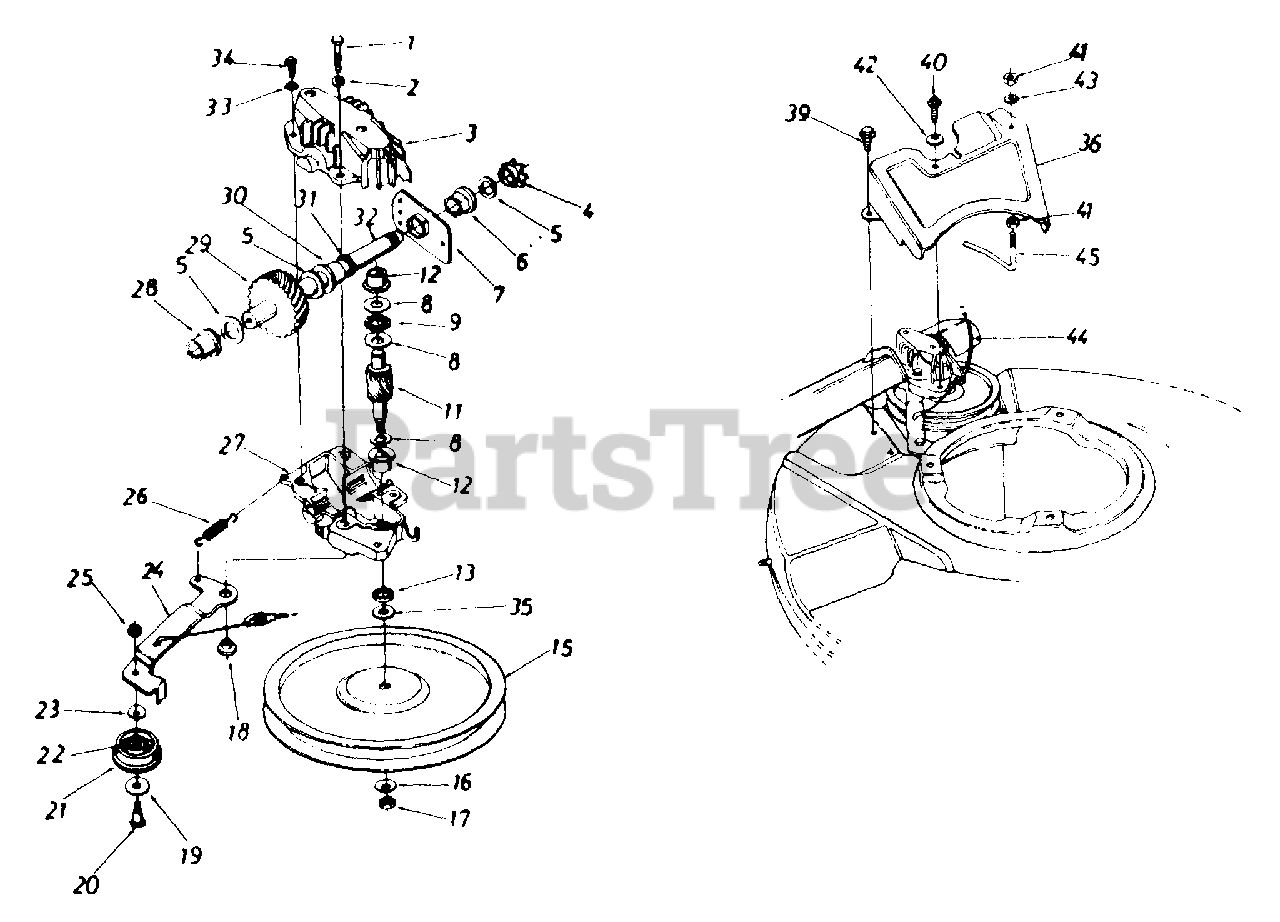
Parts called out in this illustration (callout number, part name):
1	Hex Bolt wl Patch 1/4-20 x 1.25"
2	L-Wash. 1/4" I.D.
3	Upper Hsg. Half
4	#48 Sprocket 7 Tooth x 1/2 Pitch
5	Fl-Wash. 5/8" I.D. x.030
6	Hex Flange Brg..631" I.D.
8	Thrust Wash..382" I.D. x.70" O.D.
9	Thrust Bearing .375" I.D. x .812" O.D.
11	11 Tooth Helical Gear
12	Flange Bearing
13	Oil Seal
15	Fl-Pulley 5.06" I.D.
16	Bell-Wash..265" I.D. x .75"
17	Hex Nut 1/4-28 L.H. Thd.
18	Shld. Spacer .375" Dia. x .170
19	Fl-Wash..390" I.D. x 1.0"
20	Shld. Bolt .375" Dia. x .40"
21	Fl-Idler Plastic 1.50" Dia.
22	Needle Brg..375" x .31"
23	Bell-Wash..265" I.D. x .75"
24	Idler Brk't. Ass'y.
25	Hex Patch L-Nut 1/4-28 Thd.
26	Extension Spring 1.12" Lg.
27	Lower Hsg. Half
28	Flange Bearing .56 Dia.
29	33 Tooth Helical Gear
30	Flange Bearing .629 Dia.
31	Oil Seal .625 Dia.
32	Gear Sprocket Shaft
33	L-Wash. #10 I.D.
34	Hex B-Tap Scr. #10 x .62"
35	Hex Washer .26" x .88"
40	Hex B-Tap Scr. 1/4 x .62" Lg.
41	Hex Nut 1/4-20 Thd.
42	Bell-Wash..265" I.D. x .75"
43	L-Wash. 1/4" I.D.
44	S.P. Cable 48" Lg.
45	S.P. Belt Guard
